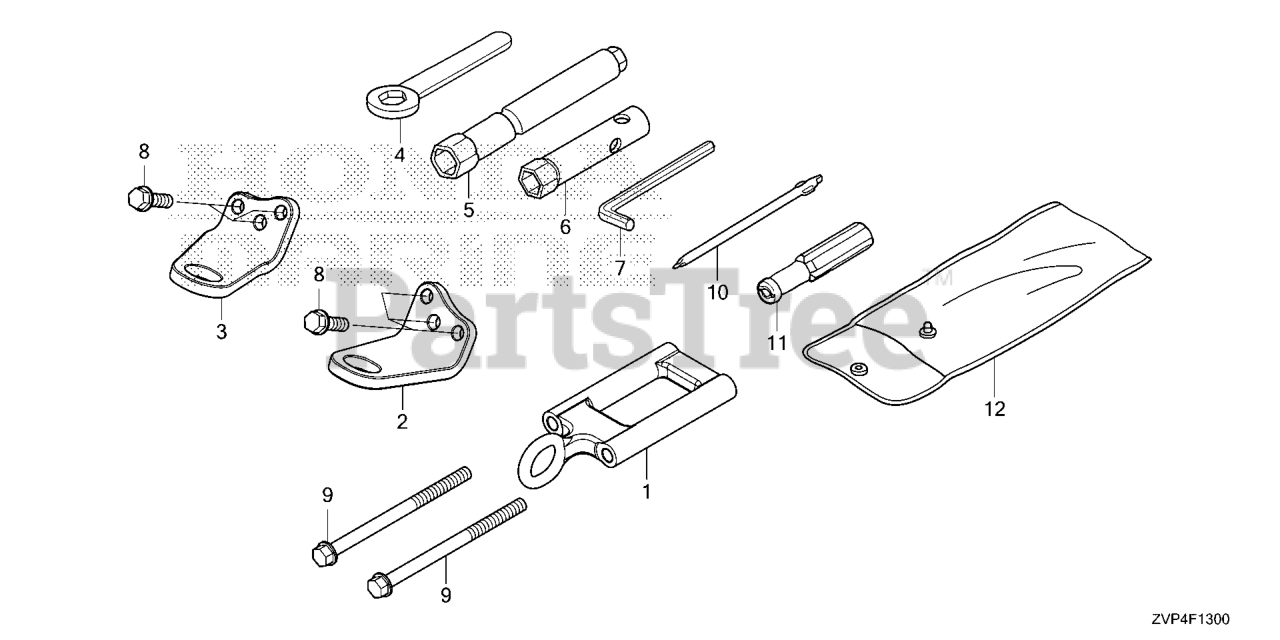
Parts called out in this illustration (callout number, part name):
1	HANGER, ENG A
2	HANGER, ENG R
3	HANGER, ENG L
4	WRENCH, EYE (14MM)
5	WRENCH, PLUG (14)
6	WRENCH, BOX (10MM) (NOT AVAILABLE)
7	WRENCH, HEX. (6MM)
8	BOLT, FLANGE (10X30)
9	BOLT, FLANGE (10X150)
10	SCREWDRIVER 1, PHILLIPS (NO.2)
11	GRIP, SCREW DRIVER
12	BAG, TOOL (200MM)
